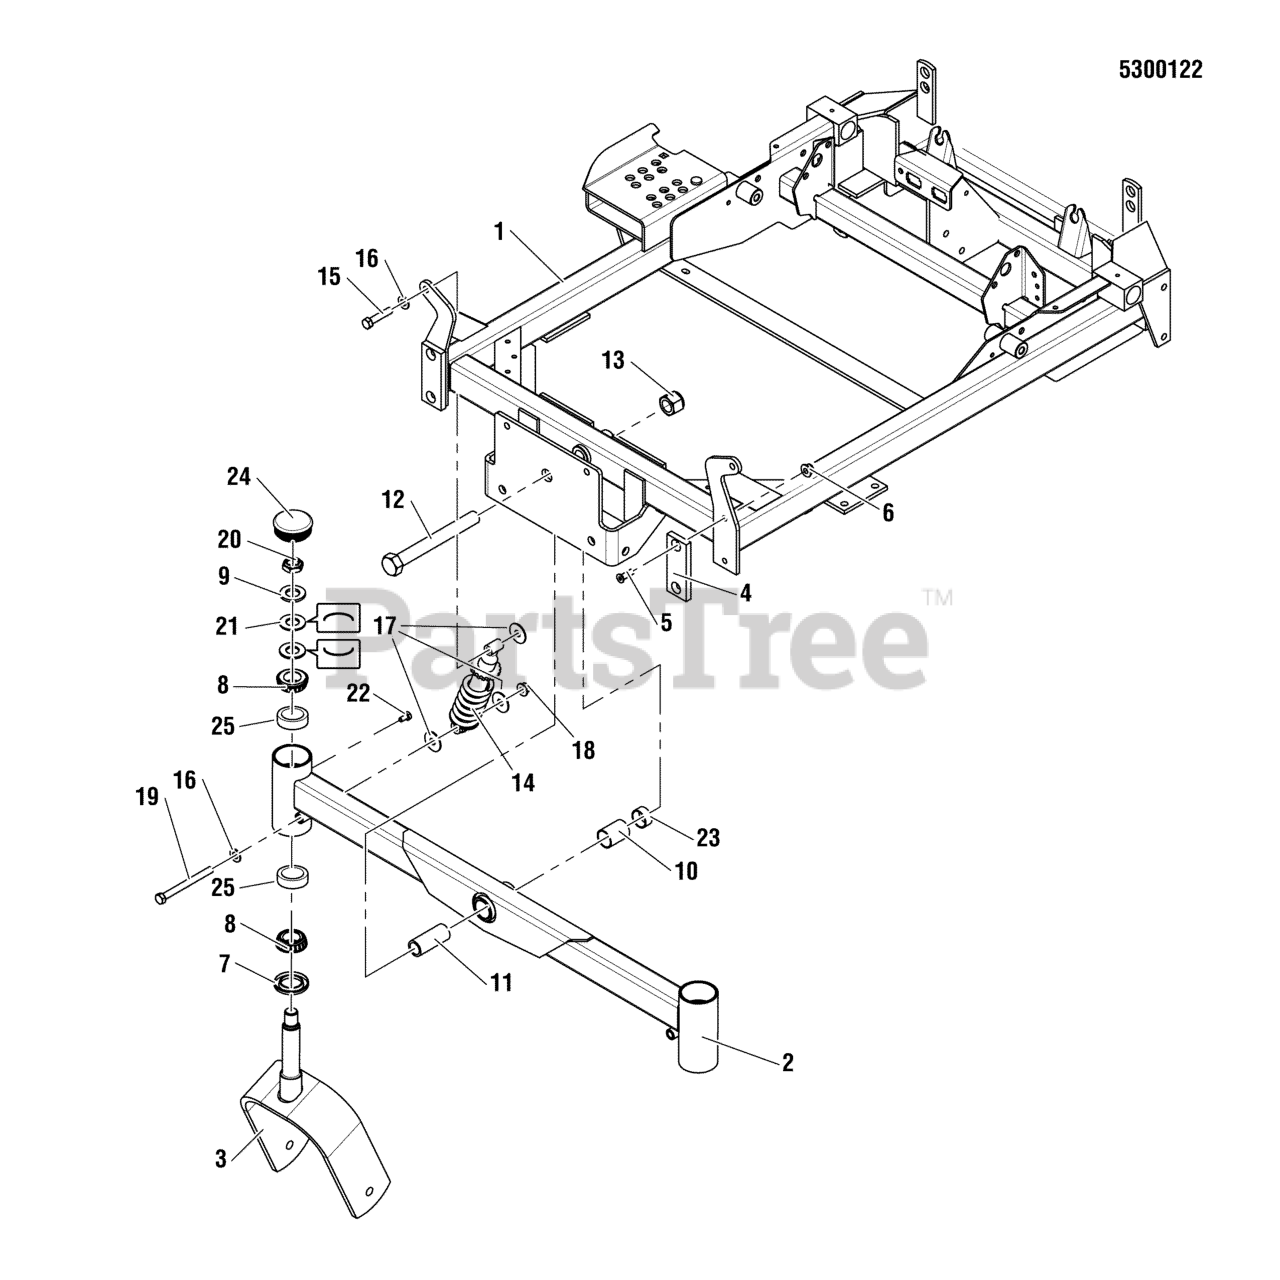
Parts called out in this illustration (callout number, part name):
1	WELD, IS1500Z MAIN FRAME - RED
2	WELD, FRONT PIVOT, IS500Z - RED
3	WELD, CASTER YOKE -RED
4	PAD, FRICTION, .375 X 1.25 X 4.00
5	SCREW, 5/16-18 X 1 PHILLIPS HD, BZ
6	NUT, 5/16-18 HEX NYLON LOCK
7	SEAL, GREASE
8	BEARING, TAPERED ROLLER, 1
9	WASHER, 3/4 SAE
10	PIVOT BEARING-1.00 X 1.125 ODX1.50
11	SPACER, .75 X 1.00 X 2.38
12	BOLT, 3/4-16 X 6-1/2 YZ GD5
13	NUT, 3/4-16 HEX NYLON LOCK
14	SHOCK, SPRING ASSEMBLY
15	BOLT, 3/8-16 X 1-3/4" GD5 CZ
16	WASHER, 3/8 SAE
17	WASHER-3/8 FENDER
18	NUT, 3/8-16 HEX NYLOCK FLANGE
19	BOLT, 3/8-16 X 4" GD5 CZ
20	NUT, 3/4-16, HEX JAM NYLON LOCK
21	WASHER, BELLEVILLE - 1.500 X .755
22	BOLT, 1/4-28 X 1/2, GD5 YZ
23	PIVOT BEARING, 1.00 X 1.125 OD X .50
24	CAP, GREASE, LOW PROFILE
25	CUP, BEARING
